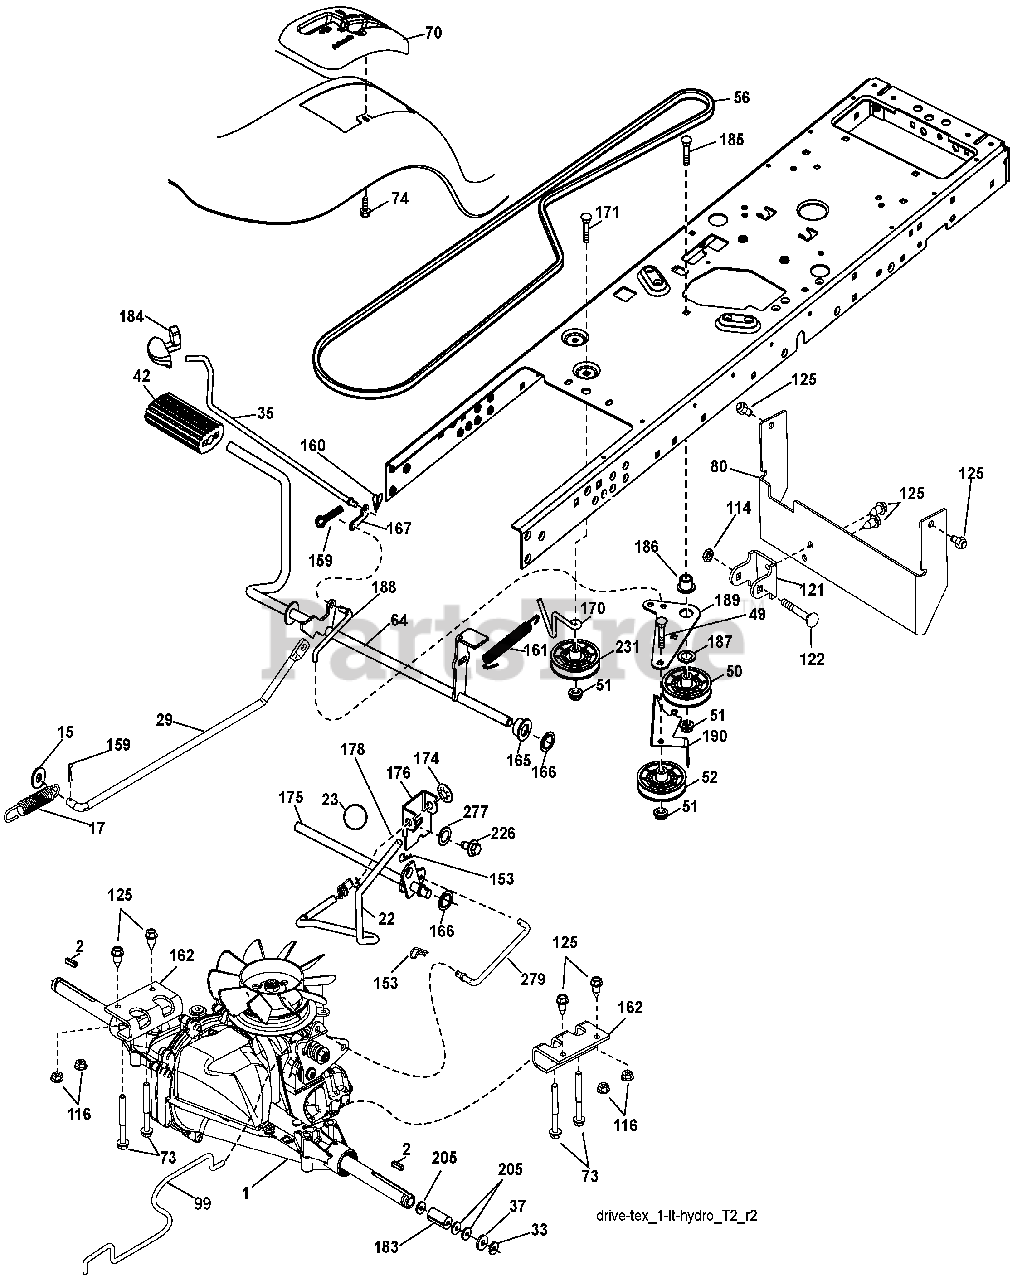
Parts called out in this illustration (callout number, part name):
1	Transaxle, Hydro Gear T2 (See Transaxle Breakdown)
2	Key Square
15	Washer 13/32 x 13/16 x 16 Ga.
17	Spring, Brake
22	Rod Shift
23	Knob
29	Rod, Brake
33	Ring E
35	Rod, Brake, Park
37	Washer 25/32 x 1-1/4 x 16 Ga.
42	Cover, Foot Pedal
49	Bolt
50	Pulley Idler Flat
51	Lock Nut 3/8-16
52	Idler V-Groove 910" Offset
56	V-Belt, Drive
64	Shaft Asm. Pedal Brake Control
70	Console
73	Bolt Hex 5/16-18 Gr. 5
74	Screw 1/4 x 1/2
80	Strap Torque
99	Rod Spring Bypass
114	Nut Lock 5/16-18 unc
116	Nut Lock Hex Flange 5/16-18
121	Bracket Strap Torque
122	Bolt 5/16-18 x 2.50
125	Screw 5/16-18 x 3/4
153	Retainer Spring 1"
159	Pin Cotter 1/8 x 3/4
160	Retainer Clip
161	Spring, Return, Clutch
165	Bushing
166	Nut Push .625
167	Latch Brake Parking
170	Keeper Belt Centerspan
171	Bolt
174	Nut Push
175	Shaft Asm Shift
176	Arm Clevis Rod Shift
178	Spring Shift
183	Spacer Axle
184	Handle Parking Brake
185	Bolt
186	Spacer Retainer
187	Washer
188	Link Clutch Ground Drive
189	Bellcrank Ground Drive
190	Keeper Bellcrank Ground Drive
205	Washer 25/32 x 1-5/8 x 16 Ga.
226	Bolt 7/16-14 x 1 Gr. 5
227	Washer Serrated
231	Idler V-Groove 1.688" Offset
279	Link Shift
